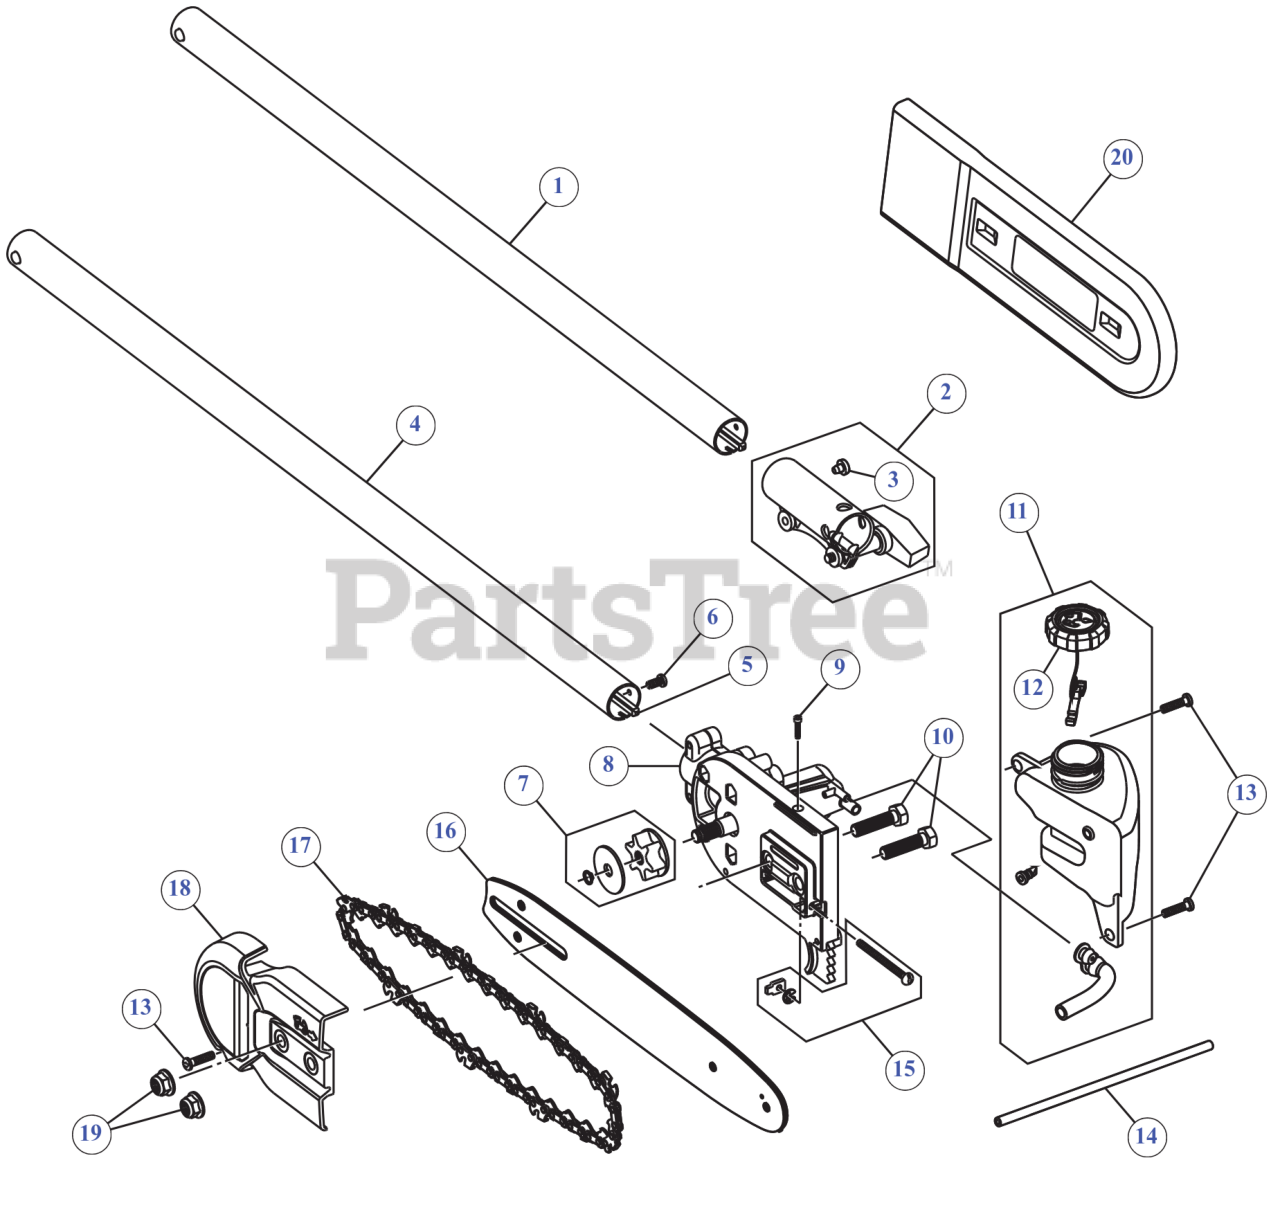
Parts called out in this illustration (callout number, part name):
1	EXTENSION BOOM
2	COUPLER ASSEMBLY
3	SCREW, 10-32X.250 TA
4	LOWER SHAFT HOUSING
5	FLEXIBLE DRIVE SHAFT
6	SCREW 1/4-20 X.500
7	SPROCKET ASSEMBLY
8	GEAR BOX ASSEMBLY
9	SCREW 4X40X.50
10	SCREW 5/16-18 x 1.25 GR5
11	OIL TANK
12	OIL CAP
13	SCREW, #8-16X.750 PH
14	OIL LINE
15	CHAIN TENSION HDW
16	BAR 10"
17	CHAIN 10"
18	GUARD CHAIN
19	FLANGE LOCK NUT 5/16-18
20	SCABBARD
